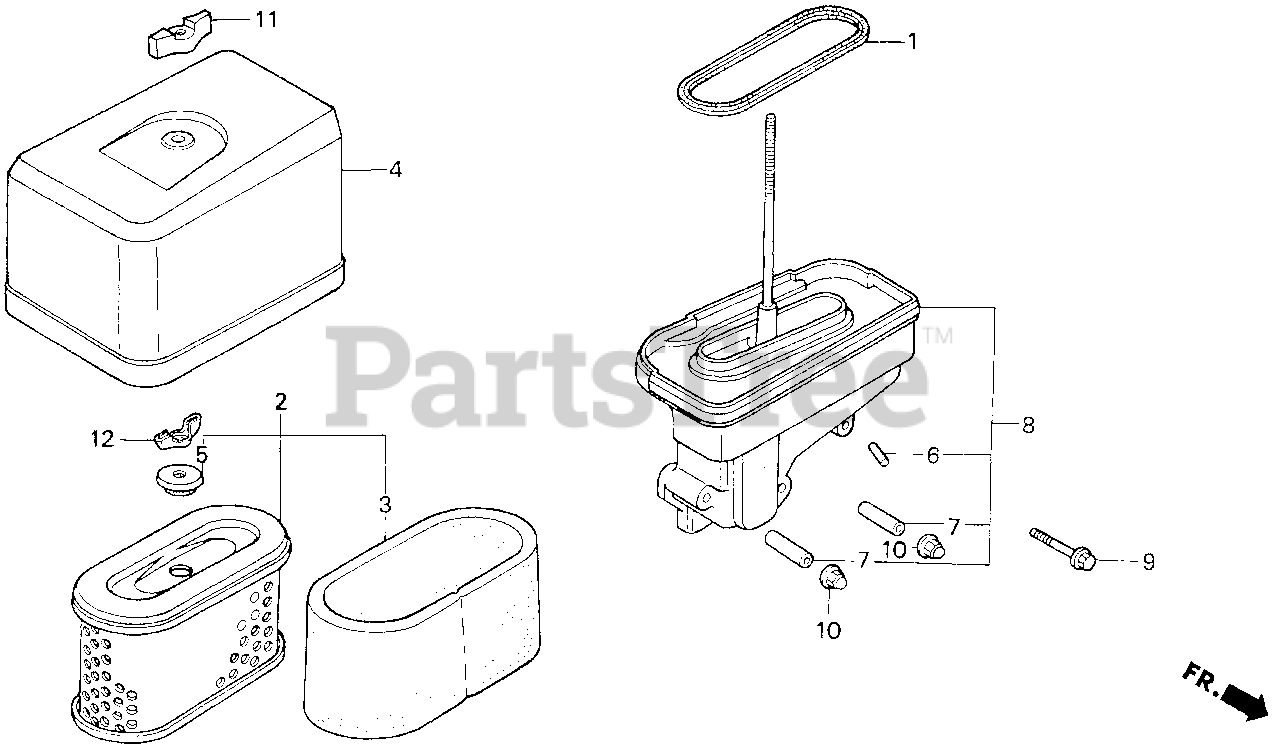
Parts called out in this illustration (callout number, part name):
1	GASKET, ELBOW
2	ELEMENT, AIR CLEANER
2	ELEMENT, AIR CLEANER (METAL BASE)
3	FILTER (OUTER)
4	COVER, AIR CLEANER (DUAL)
5	GROMMET, AIR CLEANER
6	COLLAR, AIR CLEANER
7	COLLAR, AIR CLEANER
8	ELBOW SET, AIR CLEANER
8	ELBOW, AIR CLEANER
9	BOLT, FLANGE (6X35)
10	NUT, CAP (6MM)
11	WINGNUT
12	WINGNUT, TOOL BOX SETTING
